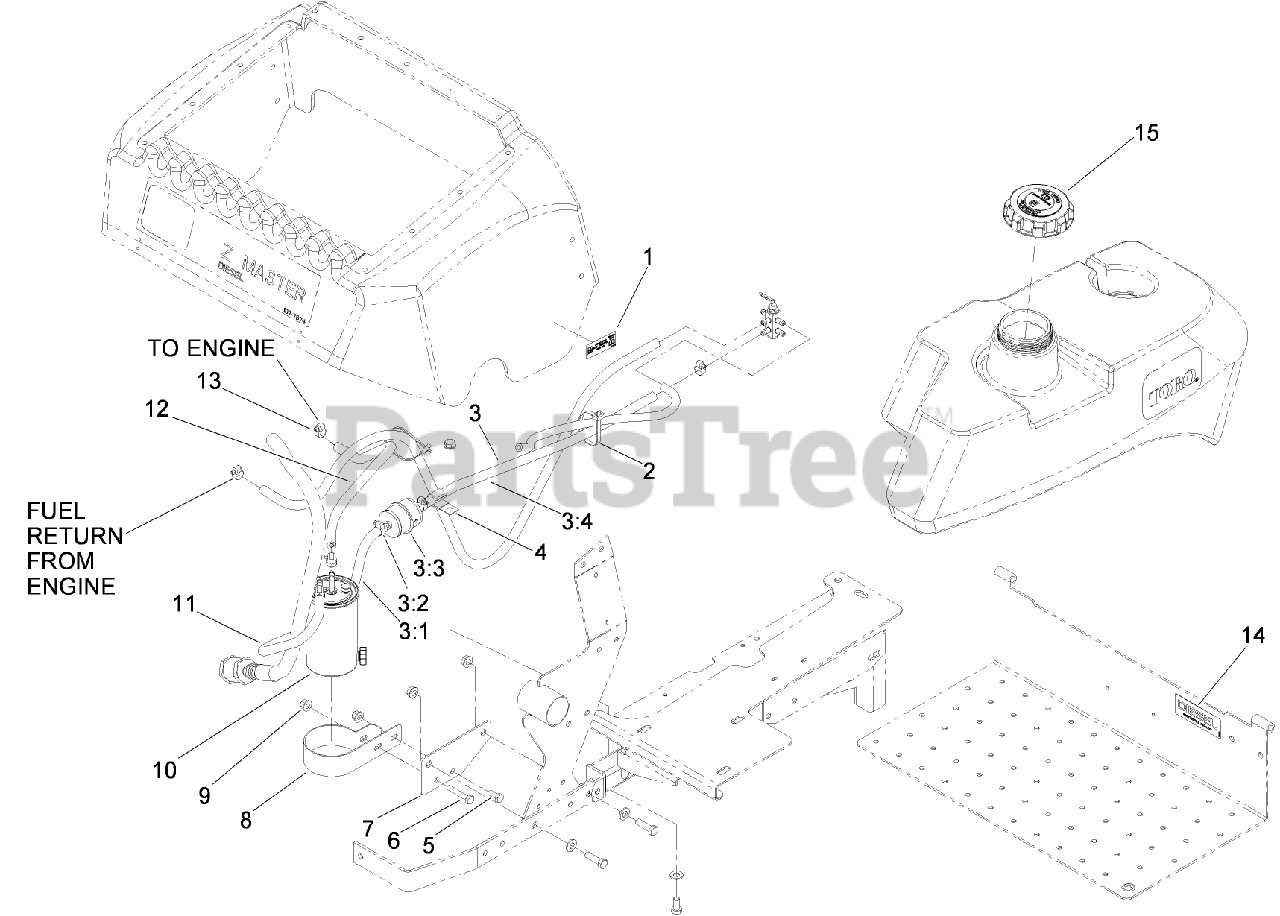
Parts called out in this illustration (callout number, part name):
1	DECAL-LOW SULFUR
2	TIE-PLASTIC
3	FUEL HOSES AND FILTER ASM (Not serviced separately)
3:1	HOSE-FUEL
3:2	CLAMP-WORM
3:3	FILTER-INLINE
3:4	HOSE-FUEL
4	CLAMP-J
5	SCREW-HH
6	SCREW-HH
7	PLATE-FUEL FILTER MOUNT
8	BRACKET-FILTER, FUEL
9	NUT-LOCK, NI
10	ELEMENT-FILTER, FUEL/WATER
11	HOSE-FUEL
12	HOSE-FUEL
13	CLAMP-WORM
14	DECAL-DIESEL, BIO-READY
15	BIODIESEL CAP ASM
